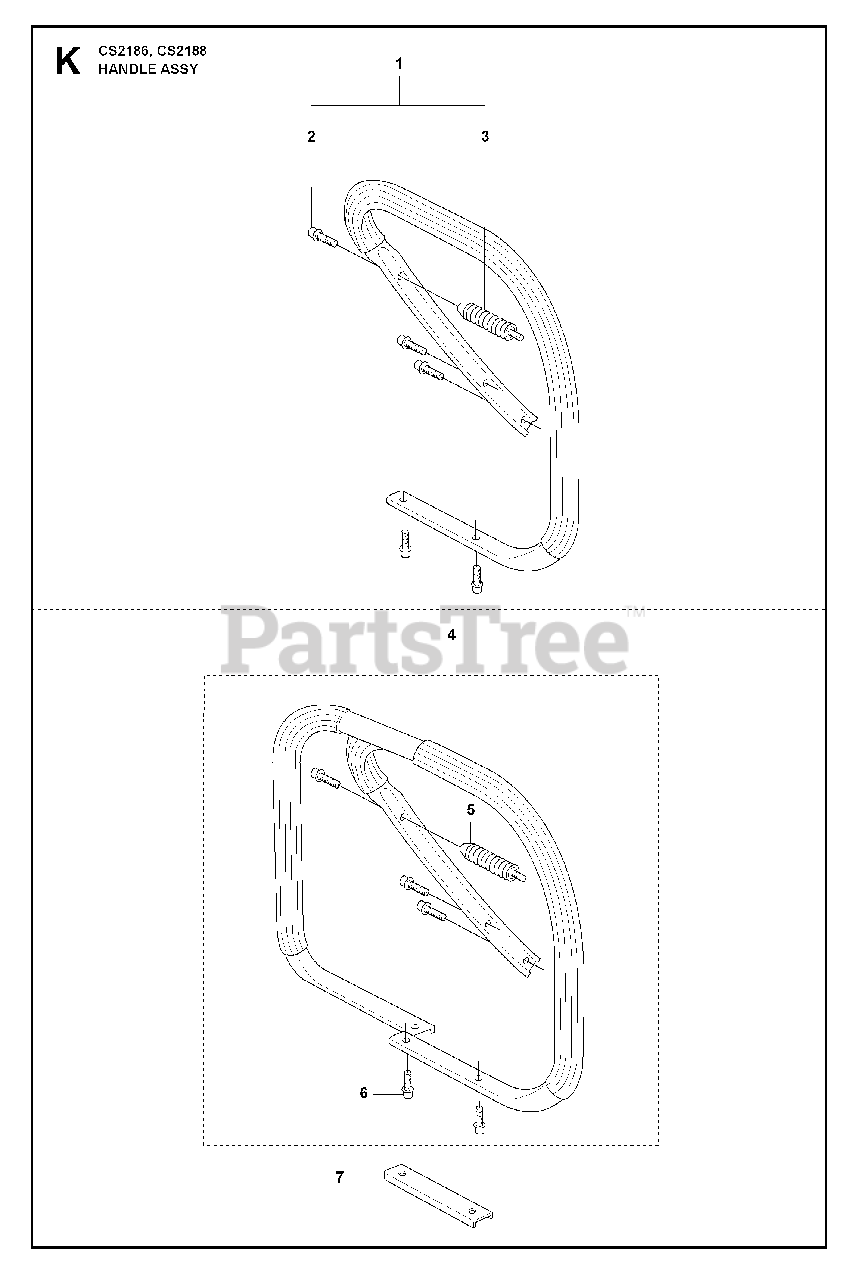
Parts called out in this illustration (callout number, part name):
1	HANDLE HEATED
2	%SCREW
3	SPRING
5	SPRING
6	%SCREW
